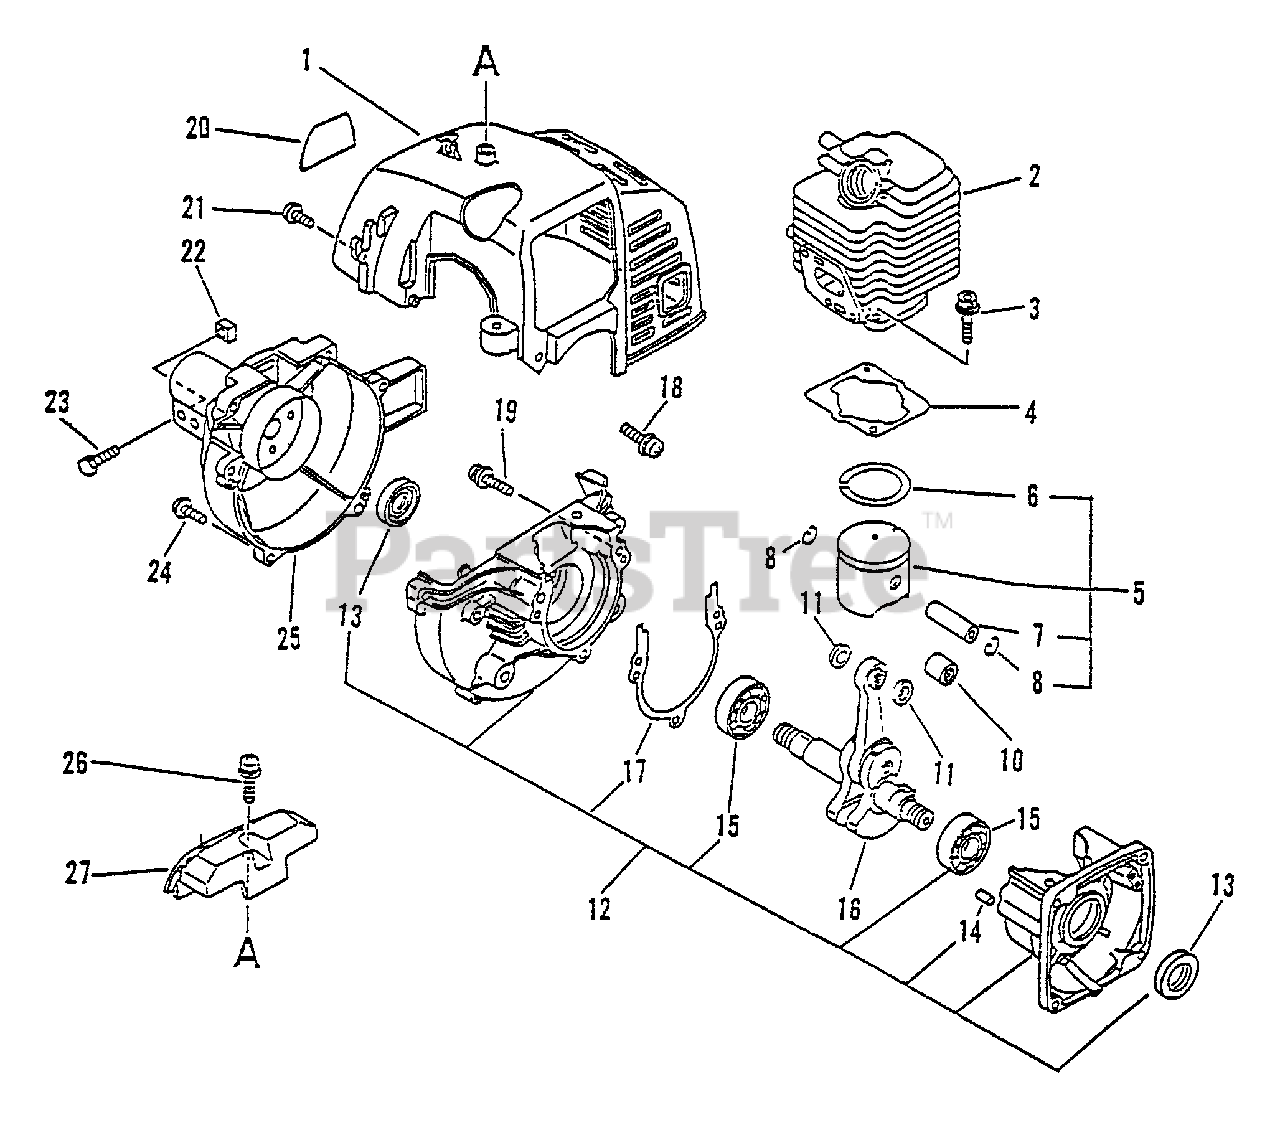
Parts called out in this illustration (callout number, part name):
1	COVER, ENGINE - GRAY
2	CYLINDER
3	SCREW - 5X22
4	GASKET, CYLINDER
5	PISTON KIT
6	RING, PISTON
7	PIN, PISTON
8	RING, RETAINING
10	BEARING, NEEDLE
11	SPACER, PISTON
12	CRANKCASE KIT
13	SEAL, OIL
14	PIN - LOCATING
15	BEARING, BALL - 6201
16	CRANKSHAFT ASSY
17	GASKET, CRANKCASE
18	SCREW - 4X12 -- TAPPING
19	SCREW - 5X28
20	LABEL - MODEL
21	SCREW - 4X16
22	NUT - 5 -- SQUARE
23	BOLT - 5X28
24	SCREW - 4X18
25	FAN CASE ASSY
26	SCREW - 5X16 -- TAPPING
27	GUARD, TOP - GRAY
